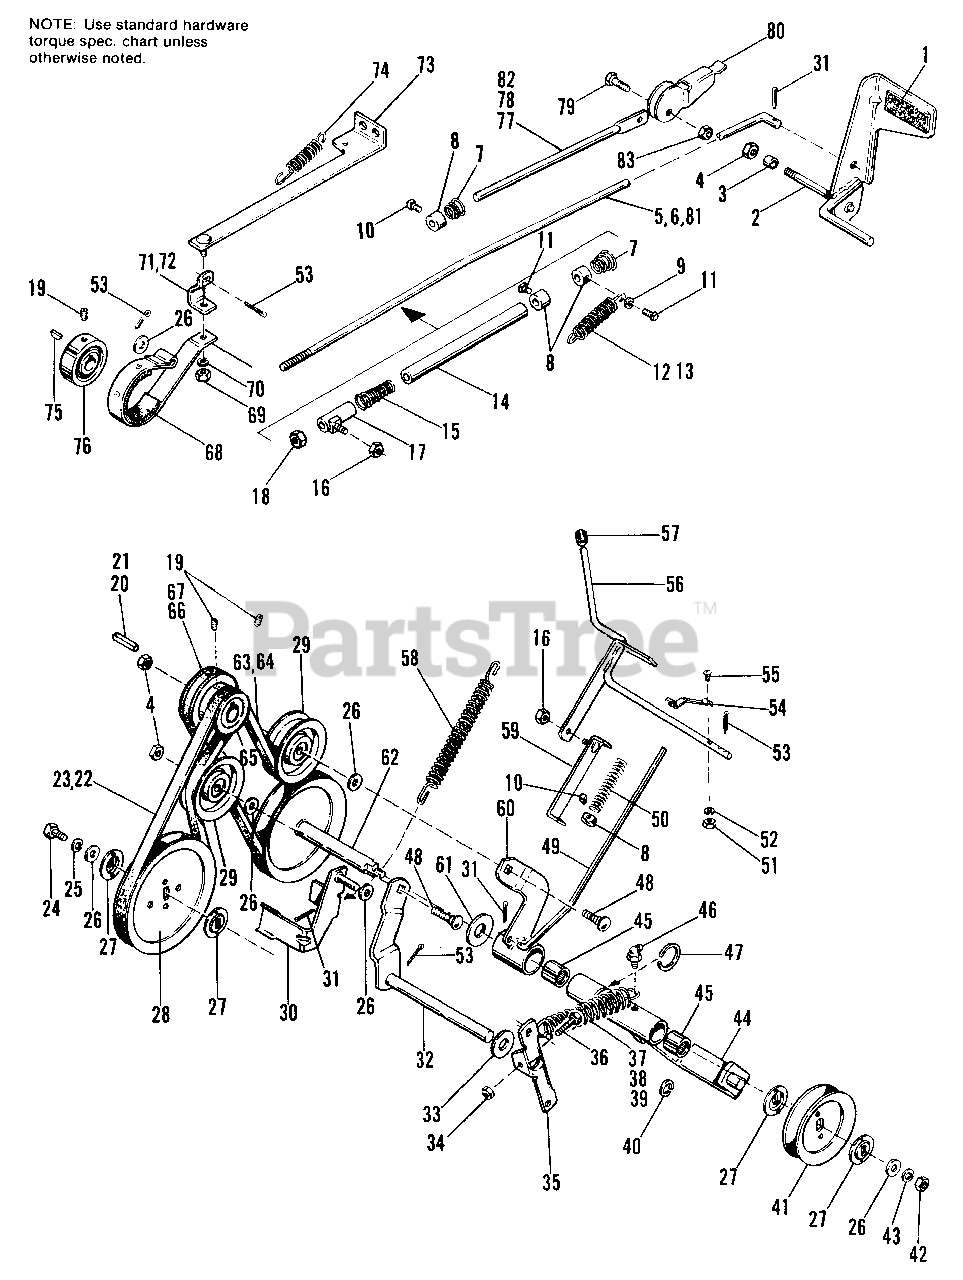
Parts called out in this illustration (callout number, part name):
1	PAD, Pedal
2	PEDAL ASSY., Foot
4	LOCKNUT, Hex, 3/8-16
5	ROD, Clutch
6	ROD, Clutch
8	COLLAR, Set
9	WASHER, Plain, 3/16
10	SETSCREW, 1/4-20 x 3/8
11	SETSCREW, 1/4-20 x 5/8
12	SPRING
13	SPRING
16	LOCKNUT, Hex, 5/16-18
17	GUIDE ASSY., Rod
18	LOCKNUT, Elastic, 5/16-18
19	SETSCREW, 5/16-18 x 5/16
20	KEY
21	KEY (Used on 1690128)
22	BELT, V
23	BELT, V
24	CAPSCREW, Hex Hd., 5/16-18 x 7/8
25	LOCKWASHER, 5/16
26	WASHER, Plain, 5/16
27	WASHER, Special
29	PULLEY, Idler
30	BRAKE ASSY., P.T.O.
31	PIN, Cotter, 3/32 x 1
32	ARM ASSY., Idler
33	WASHER, Plain, 7/16
34	LOCKNUT, Hex, 1/4-20
35	LEVER, Brake & Clutch
36	CAPSCREW, Hex Hd., 1/4-20 x 1
37	SPRING
38	SPRING (Used on 1690124 & 1690240)
39	SPRING (Used on 1690128 & 1690242)
40	RING, Retaining
42	NUT, Hex, Full, 3/8-16
43	LOCKWASHER, 3/8
44	HOUSING ASSY.
45	BEARING, Needle
46	FITTING, Grease
47	RING, Retaining
48	BOLT, Carriage, 3/8-16 x 1
49	ROD, Clutch
51	NUT, Hex, Mach. #10-32
52	LOCKWASHER, #10
53	PIN, Cotter, 1/8 x 1 (Qty. 3 used on 1690128)
54	SPRING, Clip
55	SCREW, Mach., #10-32 x 3/4
56	HANDLE ASSY., Control
59	GUIDE ASSY., Rod
60	LEVER ASSY., Idler
62	SHAFT ASSY., Pulley
63	BELT, V
64	BELT, V
65	PULLEY, Transmission Drive
66	PULLEY, Engine
67	PULLEY, Engine
68	BAND ASSY., Brake
69	NUT, Hex, Full, 1/4-20
70	LOCKWASHER, 1/4
71	LEVER, Brake
72	LEVER, Brake
73	GUIDE ASSY., Brake
75	KEY, 5/32 x 5/8
76	DRUM, Brake
77	ROD, Brake
78	ROD, Brake (Used on 1690128)
79	CAPSCREW, Hex Hd., 1/4-20 x 5/8
81	ROD, Clutch (Used on 1690242)
82	ROD, Brake (Used on 1690242)
83	LOCKNUT, Hex, 1/4-20
